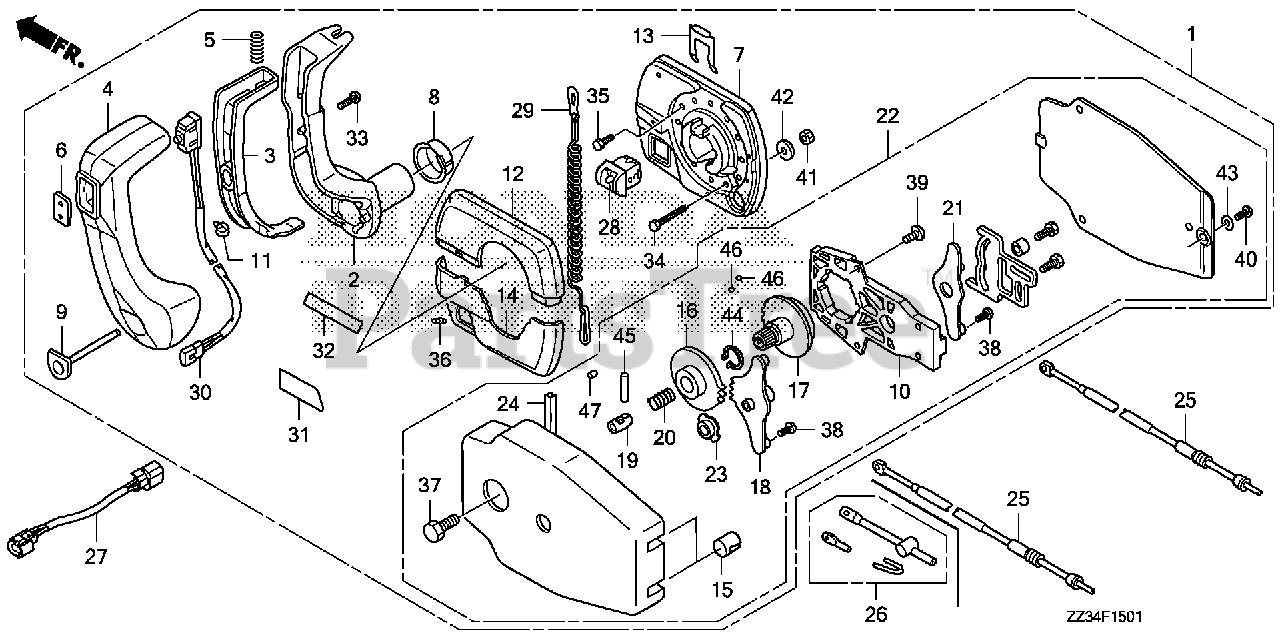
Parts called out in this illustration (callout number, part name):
1	BOX ASSY., REMOTE CONTROL (PANEL MOUNT) (NA USE ALT:06240-ZW7-U00)
2	HANDLE, REMOTE CONTROL
3	LEVER, HANDLE LOCK
4	GRIP, REMOTE CONTROL HANDLE
5	SPRING, REMOTE CONTROL HANDLE
6	COVER, GRIP
7	HOUSING ASSY., REMOTE CONTROL BOX (A)
8	BUSHING
9	BUTTON, THROTTLE
10	FRAME ASSY., REMOTE CONTROL BOX
11	BAND B, CABLE
12	HOUSING, REMOTE CONTROL BOX (B)
13	RETAINER
14	HOUSING, REMOTE CONTROL BOX (C)
15	GROMMET
16	WHEEL, CONTROL
17	SHAFT, HANDLE (NOT AVAILABLE)
18	ARM ASSY., SHIFT LINK
19	SHAFT, GEARSHIFT
20	SPRING, GEARSHIFT
21	ARM ASSY., THROTTLE LINK
22	HOUSING ASSY. (INNER) (PANEL MOUNT)
23	BUSH
24	SPRING
25	CABLE, REMOTE CONTROL (10') (TELEFLEX)
25	CABLE, REMOTE CONTROL (10') (BRUNSWICK)
25	CABLE, REMOTE CONTROL (11') (TELEFLEX)
25	CABLE, REMOTE CONTROL (11') (BRUNSWICK) (NOT AVAILABLE)
25	CABLE, REMOTE CONTROL (12') (TELEFLEX)
25	CABLE, REMOTE CONTROL (12') (BRUNSWICK) (NOT AVAILABLE)
25	CABLE, REMOTE CONTROL (13') (TELEFLEX)
25	CABLE, REMOTE CONTROL (13') (BRUNSWICK) (NOT AVAILABLE)
25	CABLE, REMOTE CONTROL (14') (TELEFLEX)
25	CABLE, REMOTE CONTROL (14') (BRUNSWICK) (NOT AVAILABLE)
25	CABLE, REMOTE CONTROL (15') (TELEFLEX)
25	CABLE, REMOTE CONTROL (15') (BRUNSWICK) (NOT AVAILABLE)
25	CABLE, REMOTE CONTROL (16') (TELEFLEX)
25	CABLE, REMOTE CONTROL (16') (BRUNSWICK) (NOT AVAILABLE)
25	CABLE, REMOTE CONTROL (17') (TELEFLEX)
25	CABLE, REMOTE CONTROL (17') (BRUNSWICK) (NOT AVAILABLE)
25	CABLE, REMOTE CONTROL (18') (TELEFLEX)
25	CABLE, REMOTE CONTROL (18') (BRUNSWICK) (NOT AVAILABLE)
25	CABLE, REMOTE CONTROL (19') (TELEFLEX)
25	CABLE, REMOTE CONTROL (19') (BRUNSWICK) (NOT AVAILABLE)
25	CABLE, REMOTE CONTROL (20') (TELEFLEX)
25	CABLE, REMOTE CONTROL (20') (BRUNSWICK) (NOT AVAILABLE) (ALT. PNO: 24920-ZW1-003AH)
26	ADAPTER, REMOCON CABLE (N/A: USE 24931-ZW1-000)
27	HARNESS ASSY., POWER TRIM-TILT
28	SWITCH ASSY., EMERGENCY STOP
29	WIRE, EMERGENCY
30	SWITCH ASSY., POWER TRIM-TILT (A)
31	MARK, REMOTE CONTROL (A)(PANEL)
32	MARK, REMOTE CONTROL (B)(FOR STARBOARD)
32	MARK, REMOTE CONTROL (C)(FOR PORT)
33	SCREW A (NOT AVAILABLE)
34	SCREW B
35	SCREW C
36	SCREW SET (1/4-20X16")
37	BOLT
38	SCREW (8-32X3/8)
39	SCREW (10-32X5/8)
40	SCREW (10-32X5/8)
41	NUT (1/4X20)
42	WASHER
43	WASHER
44	CIRCLIP (OUTER)
45	PIN, GEARSHIFT
46	BALL, STEEL
47	ROLLER, SHIFT CLICK
